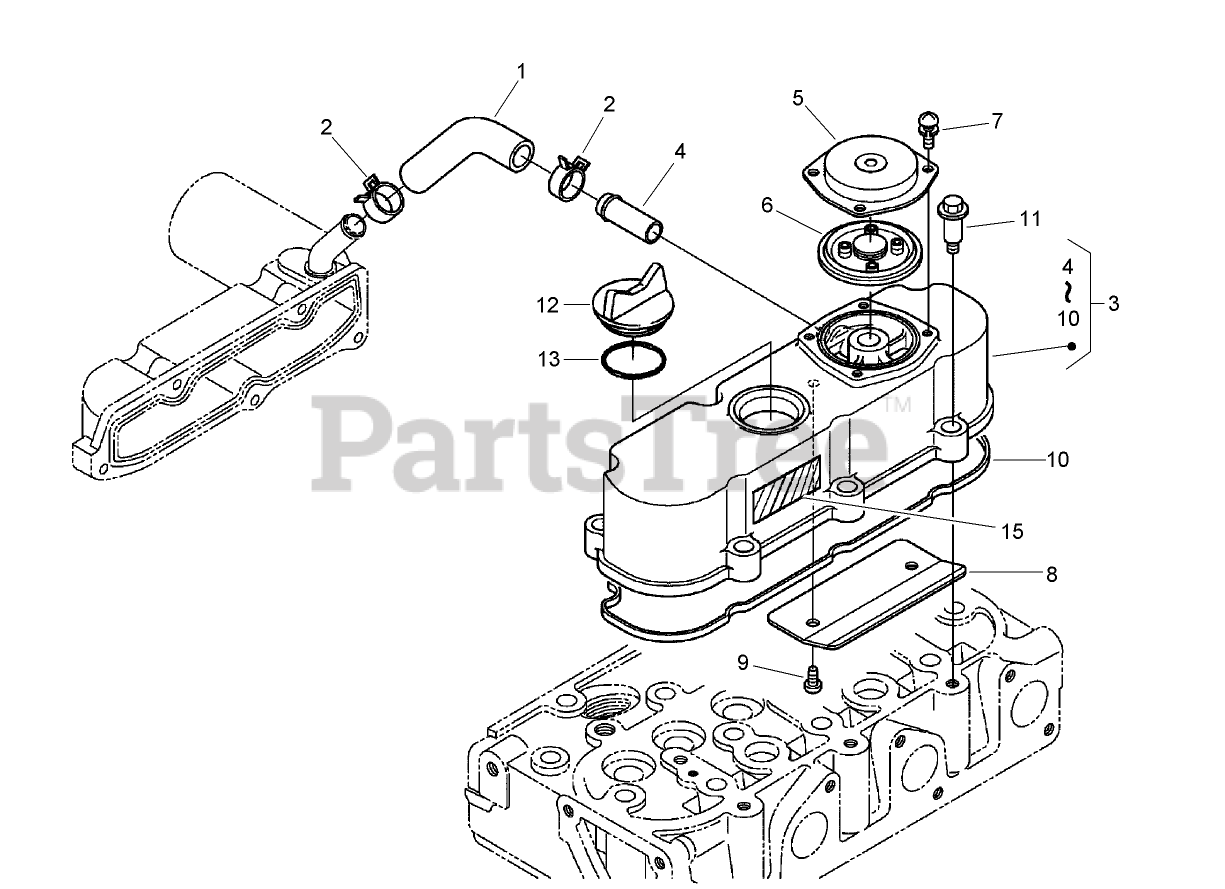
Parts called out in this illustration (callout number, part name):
1	TUBE-BREATHER
2	CLAMP-HOSE
3	CYLINDER HEAD COVER ASM
4	PIPE-RETURN, WATER
5	COVER-BREATHER
6	VALVE-BREATHER
7	SCREW (WITH WASHER)
8	SHIELD-BREATHER
10	GASKET-COVER, HEAD
12	PLUG-FILLER, OIL
13	O-RING
15	LABEL-INSTRUCTION
